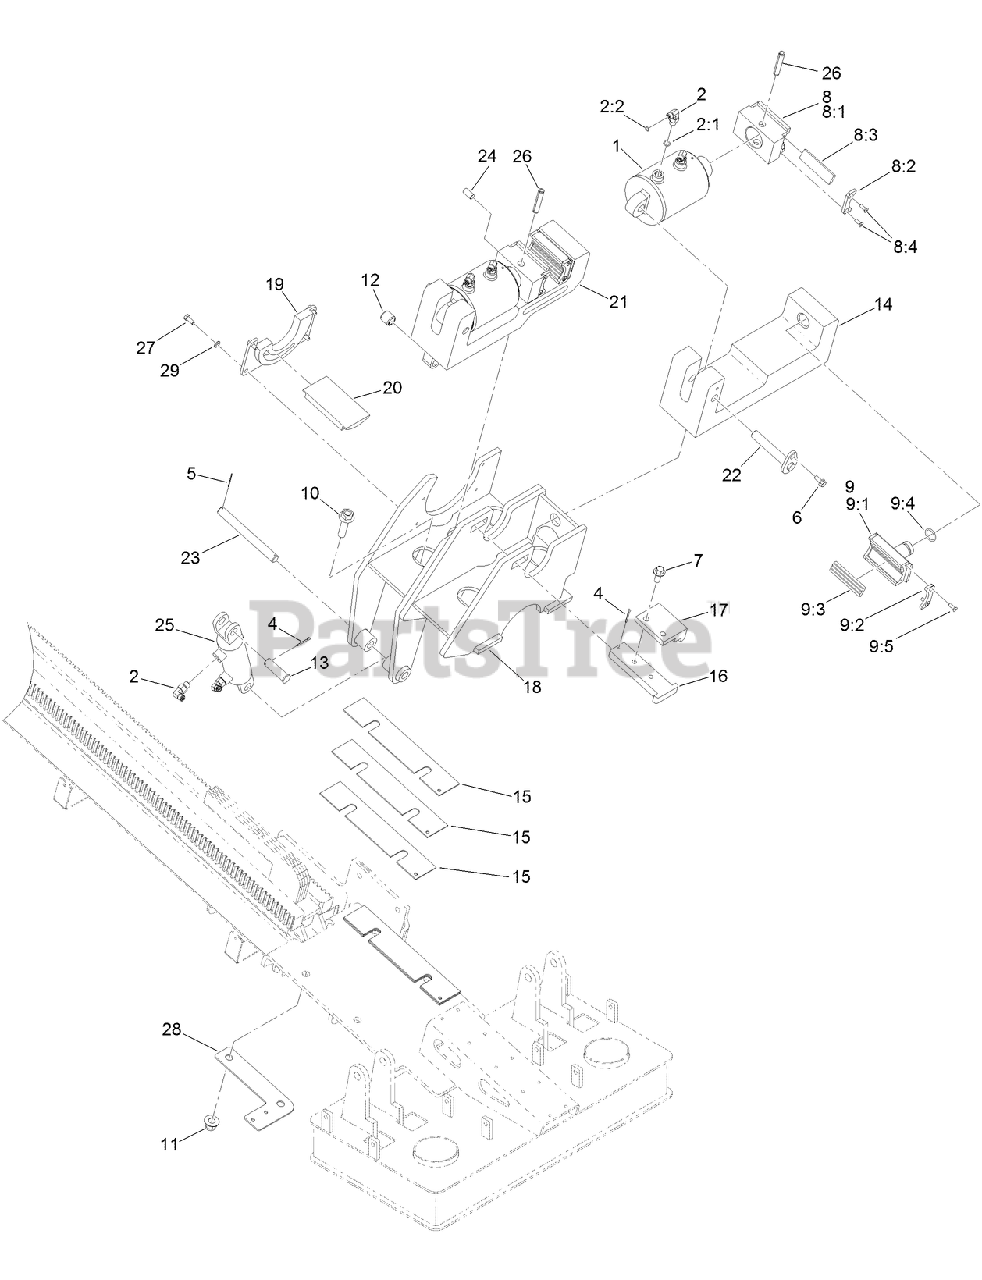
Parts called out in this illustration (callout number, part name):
1	HYD CYLINDER ASM
2	FITTING-ELBOW 90
2:1	O-RING
2:2	O-RING
4	PIN-COTTER
5	PIN-COTTER
6	SCREW-HHF
7	SCREW-HHF
8	MOVING DIE HOLDER ASM
8:1	HOLDER-DIE, MOVING
8:2	RETAINER-DIE
8:3	TONG-DIE
8:4	SCREW-FH
9	FIXED DIE HOLDER ASM
9:1	HOLDER-DIE, FIXED
9:2	RETAINER-DIE
9:3	TONG-DIE
9:4	SEAL, O-RING
9:5	SCREW-FH
10	SCREW-HHF
11	NUT-HHF
12	BUSHING-SPRING
13	PIN-CLEVIS
14	BASE-FIXED CLAMP
15	PLATE-SHIM
16	PIN-RETAINING (W/ TAP HOLES)
17	BLOCK-STOP, CYLINDER
19	RETAINER-PIVOT KEY, WRENCH
20	KEY-PIVOT, WRENCH
21	CLAMP-ROTATING, WRENCH
22	PIN-FLAGGED
23	PIN-CYLINDER
24	PIN-DOWEL
25	HYD CYLINDER ASM
26	PIN-SPRING
27	SCREW-HH
28	PLATE-MOUNT, VALVE
29	WASHER-HARDENED
